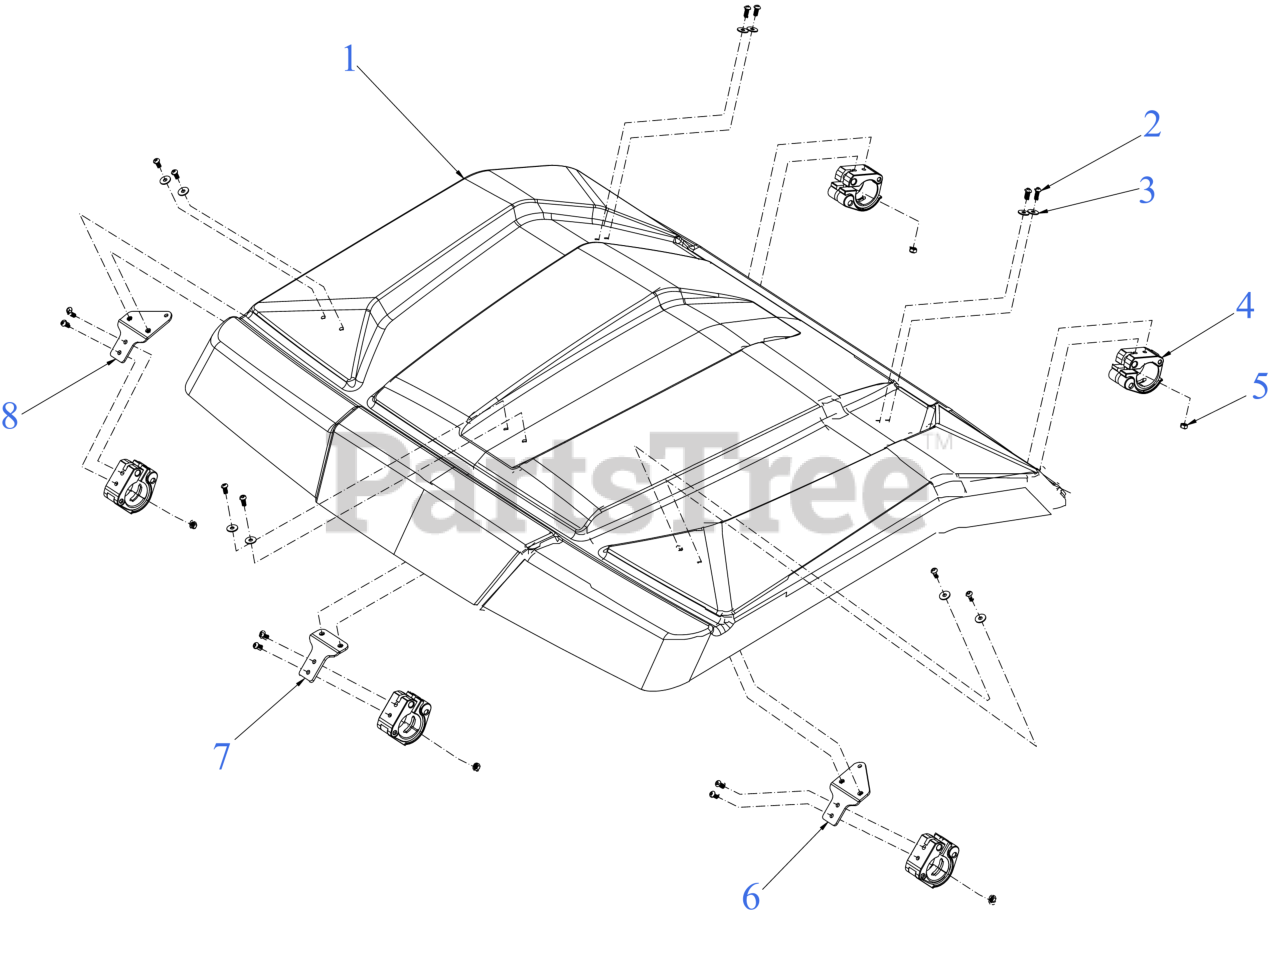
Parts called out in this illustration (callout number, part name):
1	ROOF PANEL
2	BUTTON HEAD SCREW M6x16
3	FLAT WASHER
6	ROOF BRACKET (LH)
7	ROOF BRACKET (CENTER)
8	ROOF BRACKET (RH)
